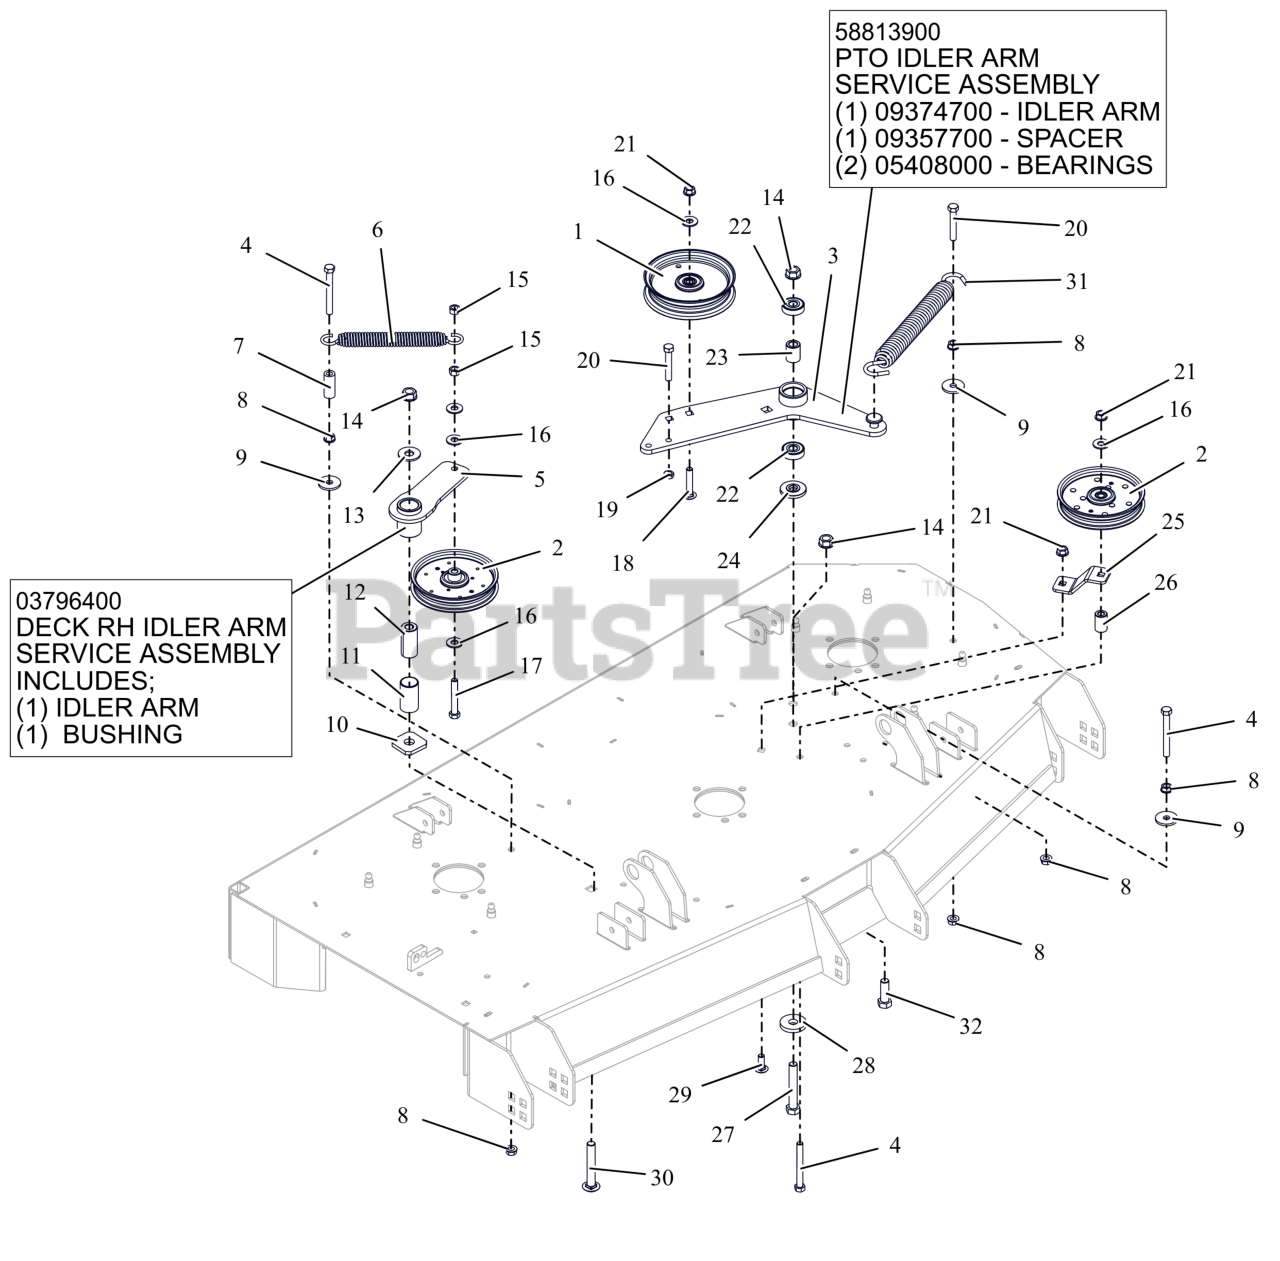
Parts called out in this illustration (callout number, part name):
1	IDLER- FLAT - 5.00" X .75"
2	IDLER- 5" FLANGED
3	PTO IDLER ARM
3	WLDMT, IDLER ARM PT660
3	SPACER .510 X .867 X 1.1485
3	BRG-BALL .500X1.38X.437
4	BLT, HEX .38-16X3.25 G5 ZCC
5	ASM, IDLER ARM (DECK)
5	WMT, IDLER ARM - BLACK
5	BSHG, 1.00X1.125X1.937
6	SPRING- EXTENSION
7	HOSE, .38 X 1.65
8	NUT, SPNLK-FLG .38-16 G5 ZCC
9	WSHR,FLT .406X1.375X.135 ZCC
10	WSHR-FLT .640X1.75X.250
11	BSHG, 1.00X1.125X1.937
12	BSHG, SPCR .502X.997X2.03 PM
13	WSHR,FLT .563X1.375X.109 ZCC
14	NUT-LK-CTR-FLG .500-13 GG ZCC
15	NUT-LK-CTR .38-16 ZC120
16	WSHR,FLT .438X1.00X.083 ZCC
17	BLT, HEX .38-16X2.50 G5 ZCC
18	BLT,RHSSN.375-16X2.00 G5 ZCC
19	NUT-JAM .375-16 G2 ZCC
20	BLT,HEX .38-16X2.25 G5 ZCC
21	NUT-LK-CTR-FLG .375-16 GF ZCC
22	BRG-BALL .500X1.38X.437
23	SPACER .510 X .867 X 1.1485
24	SPACER, IDLER ARM
25	BRKT- PTO FIXED IDLER MTG
26	BUSHING, SLV .380X.750X1.190
27	BLT,HEX .50-13X3.25 G5 ZCC
28	WSHR-FL-STL 0.557X1.625X0.25 ZCC
29	BLT,RHSSN .38-16X1.00 G5 ZCC
30	BTL,RHSSN .500-13 X 3.25 G5 ZCC
31	SPRING, EXTENSION
32	BLT,HEX .50-13X1.50 G5 ZCC
